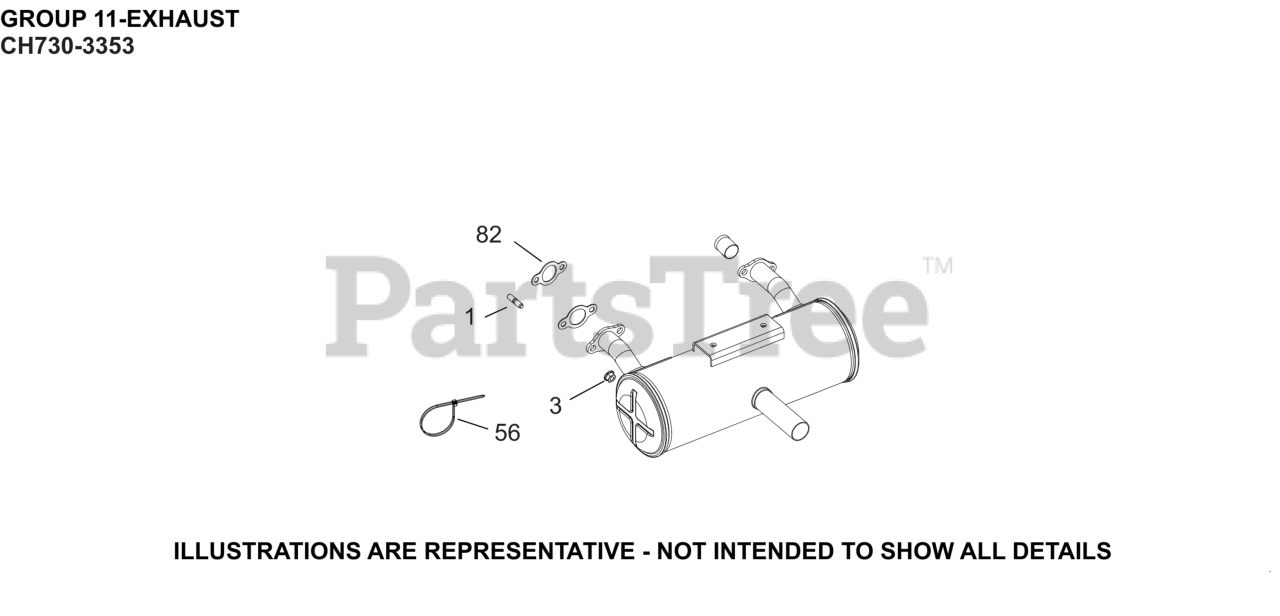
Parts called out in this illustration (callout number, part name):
1	STUD, METRIC EXHAUST
3	NUT, FLG M8X1.25
82	GASKET, EXHAUST MANIFOLD
